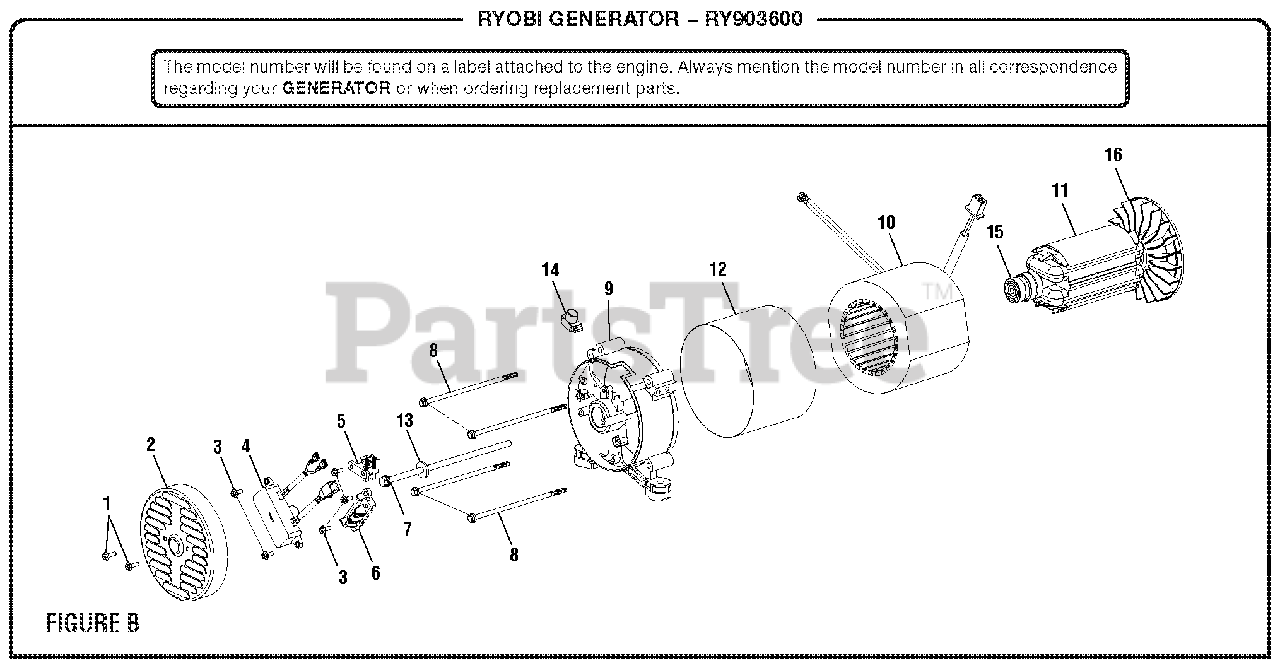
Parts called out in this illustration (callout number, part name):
1	Bolt (M5 x 12 mm, Hex Flange Hd.)
2	Brush Cover
3	Bolt (M5 x 16 mm, Hex Flange Hd.)
4	Automatic Voltage Regulator
5	Brush Assembly
6	Terminal Block
7	Rotor Bolt
8	Stator Bolt
9	Bearing Housing
10	Stator Assembly
11	Rotor Assembly
13	Rotor Washer
14	Rubber Boot
15	Ball Bearing
